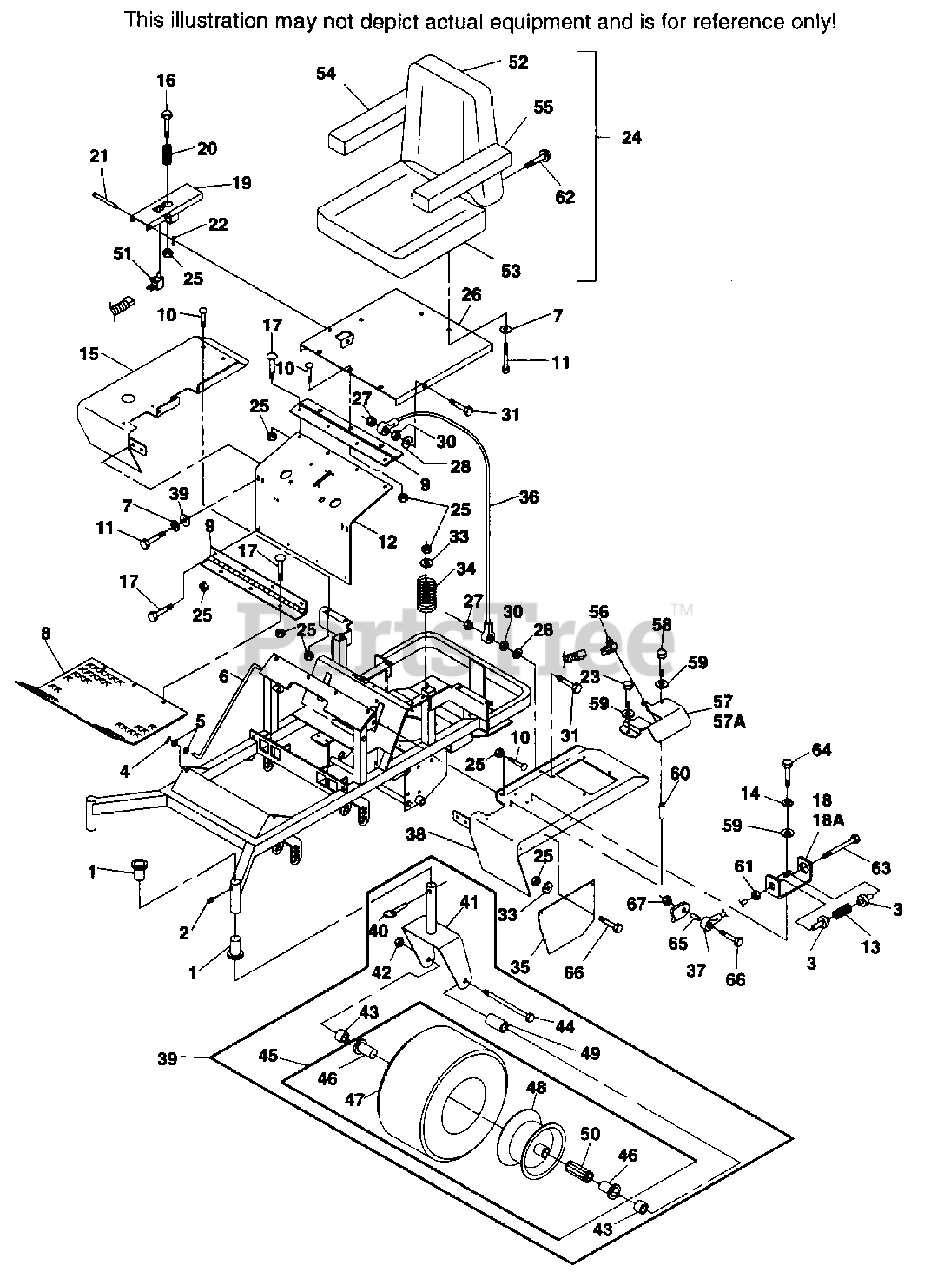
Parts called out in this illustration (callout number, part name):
1	BUSHING
2	GREASE FITTING
3	BUSHING, SPRING KEEPER
4	HAIR PIN, 1/16" DIAMETER
6	ROD, FOOT PLATE LATCH
8	FOOT PLATE
9	HINGE
12	KICK PLATE
13	NEUTRAL RETURN SPRING
14	LOCKWASHER 3/8", LH ONLY
15	FENDER ASSEMBLY, RH(WITH DECAL)
18	RETAINER, NEUTRAL SPRING, LH
18A	RETAINER, NEUTRAL SPRING, RH
19	SEAT SWITCH BRACKET
20	SPRING
21	CLEVIS PIN
22	HAIR PIN COTTER
24	SEAT
25	HEX NUT, 5/16-18 ELASTIC STOP
26	SEAT BASE
27	HEX NUT, 1/4-20 ELASTIC STOP
34	SEAT SPRING
35	FENDER PANEL, RH
36	CABLE, SEAT STOP
37	BALL JOINT, NEUTRAL
38	FENDER - LH
39	CASTER WHEEL ASSEMBLY, COMPLETE
40	QUICK PIN
41	CASTER WHEEL YOKE
42	HEX NUT, 1/2-13 ELASTIC STOP
43	SPACER
45	WHEEL ASSEMBLY, COMPLETE
46	RETAINER
47	TIRE ONLY
48	RIM ONLY
49	SLEEVE
50	ROLLER BEARING
51	SEAT SWITCH
52	SEAT BACK CUSHION
53	SEAT BOTTOM CUSHION ASSEMBLY
54	ARM PAD, RH
55	ARM PAD, LH
56	NEUTRAL INTERLOCK SWITCH
57	NEUTRAL LOCK BRACKET, RH
57A	NEUTRAL LOCK BRACKET, LH
60	SPACER, NEUTRAL LOCK BRACKET
61	HEX NUT, 3/8-24 UNF
62	HEX HEAD SCREW W/WASHER, 1/4-20 X 3/4"
63	HEX HEAD BOLT, 3/8-24 X 6-1/2", UNF
65	SPACER NEUTRAL SPRING
